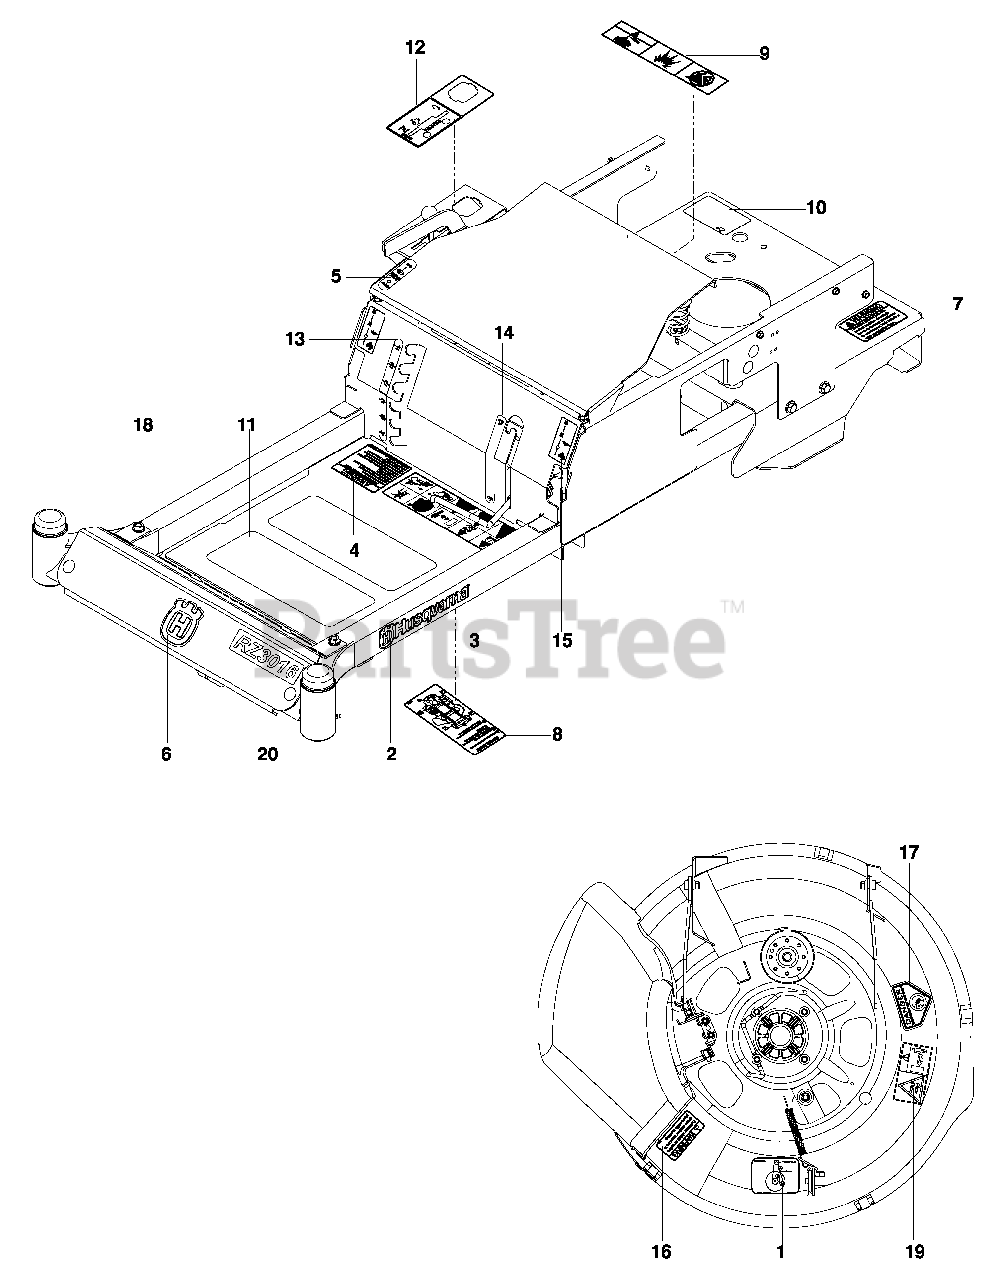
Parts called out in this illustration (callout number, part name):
1	DECAL, BELT ROUTING
2	DECAL, HUSQVARNA
3	DECAL, SAFETY WARNING
4	DECAL, WARNINGS
5	DECAL, PARK BRAKE
6	DECAL, CROWN
7	DECAL, PROP 65
8	DECAL, SERVICE
9	DECAL, BATTERY WARNING
10	DECAL, DO NOT TOW
11	PAD, ABRASIVE
12	DECAL, CONTROL PANEL
13	DECAL, DECK HEIGHT
14	DECAL, BLADE ENGAGE
15	DECAL, MOTION CONTROL
16	DECAL, WARNING
17	DECAL, BLADE WARN
19	DECAL, SEVERING
20	DECAL, RZ3016
